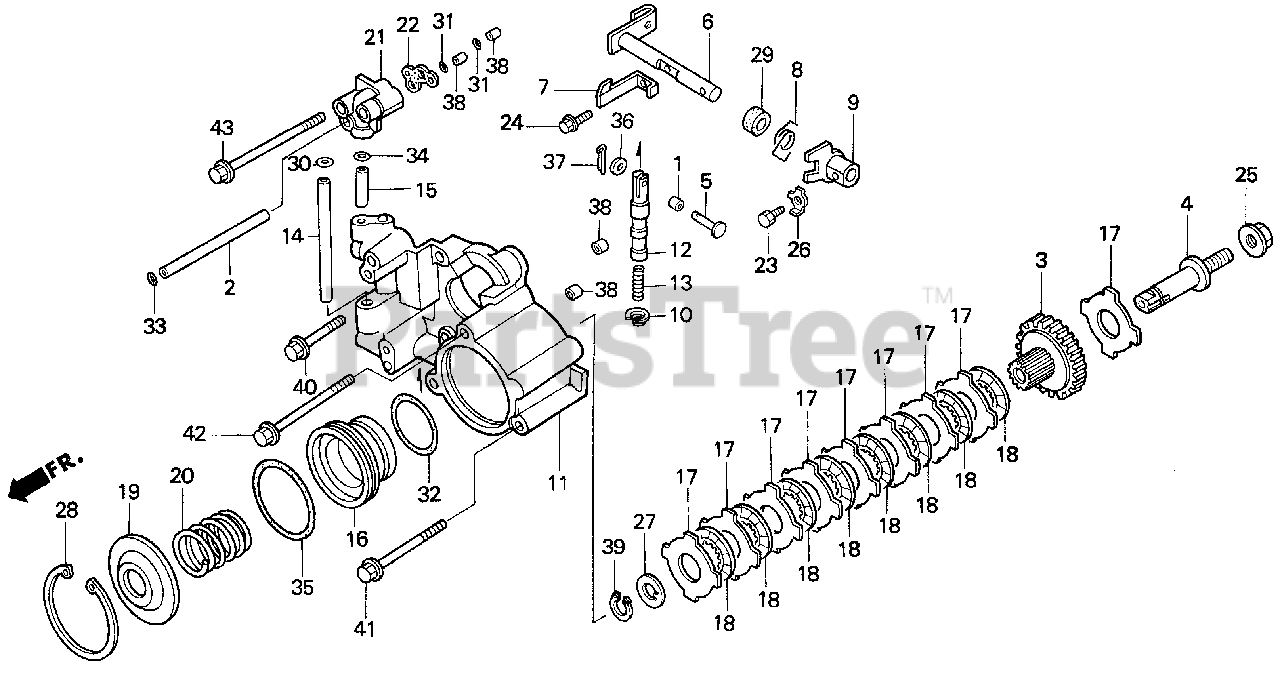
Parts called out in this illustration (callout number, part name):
2	PIPE, MAIN CLUTCH
3	SHAFT, P.T.O. BRAKE (A)
4	SHAFT, P.T.O. BRAKE (B)
5	PIN, MANUAL VALVE
6	SHAFT, P.T.O. CONTROL
7	PLATE, P.T.O. SWITCH
8	SPRING, P.T.O. CONTROL LEVER
9	LEVER, P.T.O. VALVE
10	SEAT, RELIEF VALVE SPRING
11	BODY, INDEPENDENT P.T.O.
12	VALVE, P.T.O. CONTROL
13	SPRING, P.T.O. VALVE
14	PIPE A, OIL PASSAGE
15	PIPE B, OIL PASSAGE
16	PISTON, P.T.O. BRAKE
17	PLATE, P.T.O. BRAKE
18	DISK, P.T.O. BRAKE
19	SEAT, P.T.O. BRAKE SPRING
20	SPRING, P.T.O. BRAKE
21	BODY, P.T.O. OIL PASSAGE
22	GASKET, OIL PASSAGE BODY
23	BOLT, HEX. (6MM)
24	BOLT, FLANGE (6X8)
25	NUT, SELF-LOCK (10MM)
26	WASHER, LOCK (6MM)
27	WASHER, THRUST (12X25X1)
28	CIRCLIP (INNER) (64MM)
29	OIL SEAL (12X22X7) (ARAI)
30	O-RING (7.7X2.3) (ARAI)
31	O-RING (7.5X1.5)
32	O-RING (41.8X2.2) (NOK)
33	O-RING (5.7X2.2) (ARAI)
34	O-RING (6X1.5) (NOK)
35	O-RING (59.6X2.4)
35	O-RING (59.6X.24)
36	WASHER, PLAIN (5MM)
37	PIN, COTTER (1.6X12)
38	PIN A, DOWEL (8X14)
39	CIRCLIP (OUTER) (12MM)
40	BOLT, FLANGE (6X45)
41	BOLT, FLANGE (6X75)
42	BOLT, FLANGE (6X85)
43	BOLT, FLANGE (6X100)
